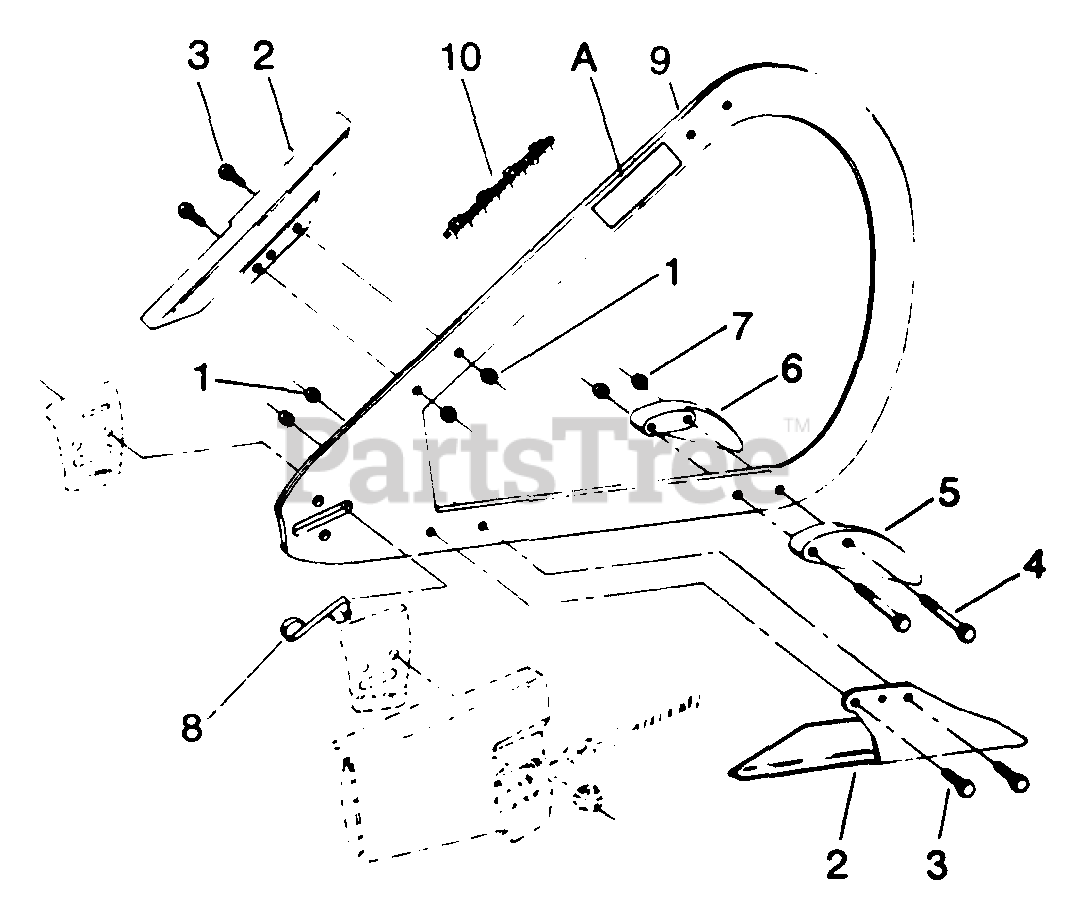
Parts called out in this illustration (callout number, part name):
1	Locknut - (12 - 24)
2	Chain Guard - Upper and Lower
3	Screw-Guard Mtg. (12-24 x 5/8-Hex Hd.)
4	Screw- Spike Mtg. (1/4-20 x 1-3/4 - Hex Hd.)
5	Bumper Spike - Right
6	Bumper Spike - Left
7	Locknut - Bumper Spike Mounting (1/4-20)
8	"S" Clip
9	Bow Guide
10	Chain
A	Decal - Bow Guide Warning
